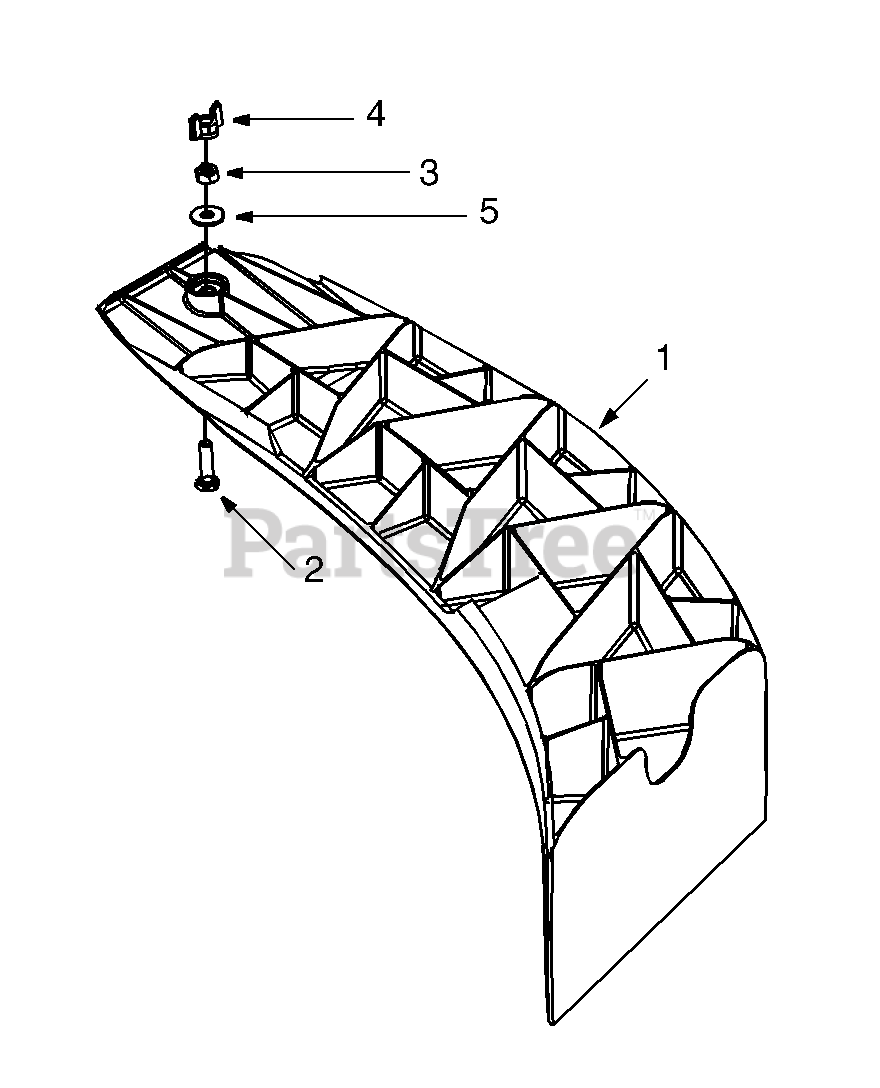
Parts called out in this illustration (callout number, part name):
1	Mulching Plug
2	Hex Screw 1/4"
3	Hex Nut: 1/4-20
4	Wing Nut
5	Flat Washer
